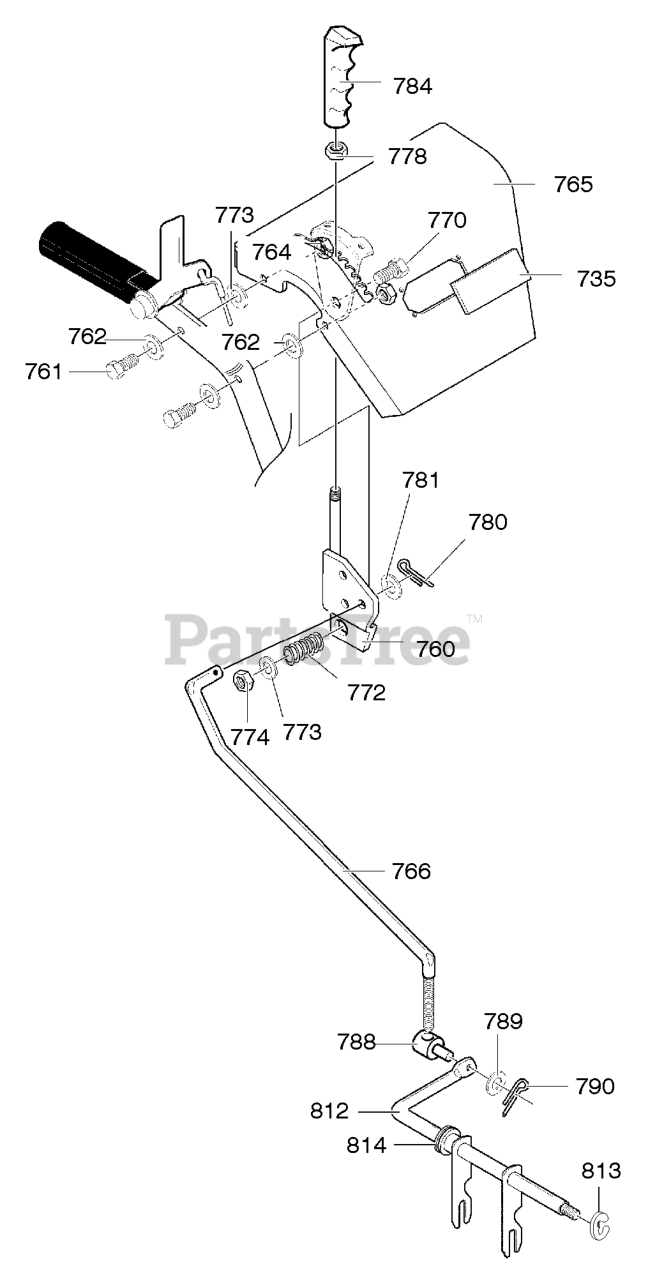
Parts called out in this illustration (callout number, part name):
735	PLATE, BLANKING LIGHT
760	HANDLE ASSY SPD CTRL
761	SCREW, 5/16-18 x 1.75
762	FLATWASHER
764	NUT, 5/16-18 HEXWDFLLK
765	ASSEMBLY, PANEL
766	ROD, SPEED CONTROL
770	SCREW 3/8-16X2.00
773	FLATWASHER
774	NUT, 3/8-16 HEXNYL
778	NUT, 3/8-16 REGHEX
781	FLATWASHER
784	HANDLE 3/8-16
788	NUT, TRUNNION
789	FLATWASHER
790	COTTER PIN
812	ROD, ASSY YOKE
813	RING, RETAINER
814	BEARING, FLANGE
